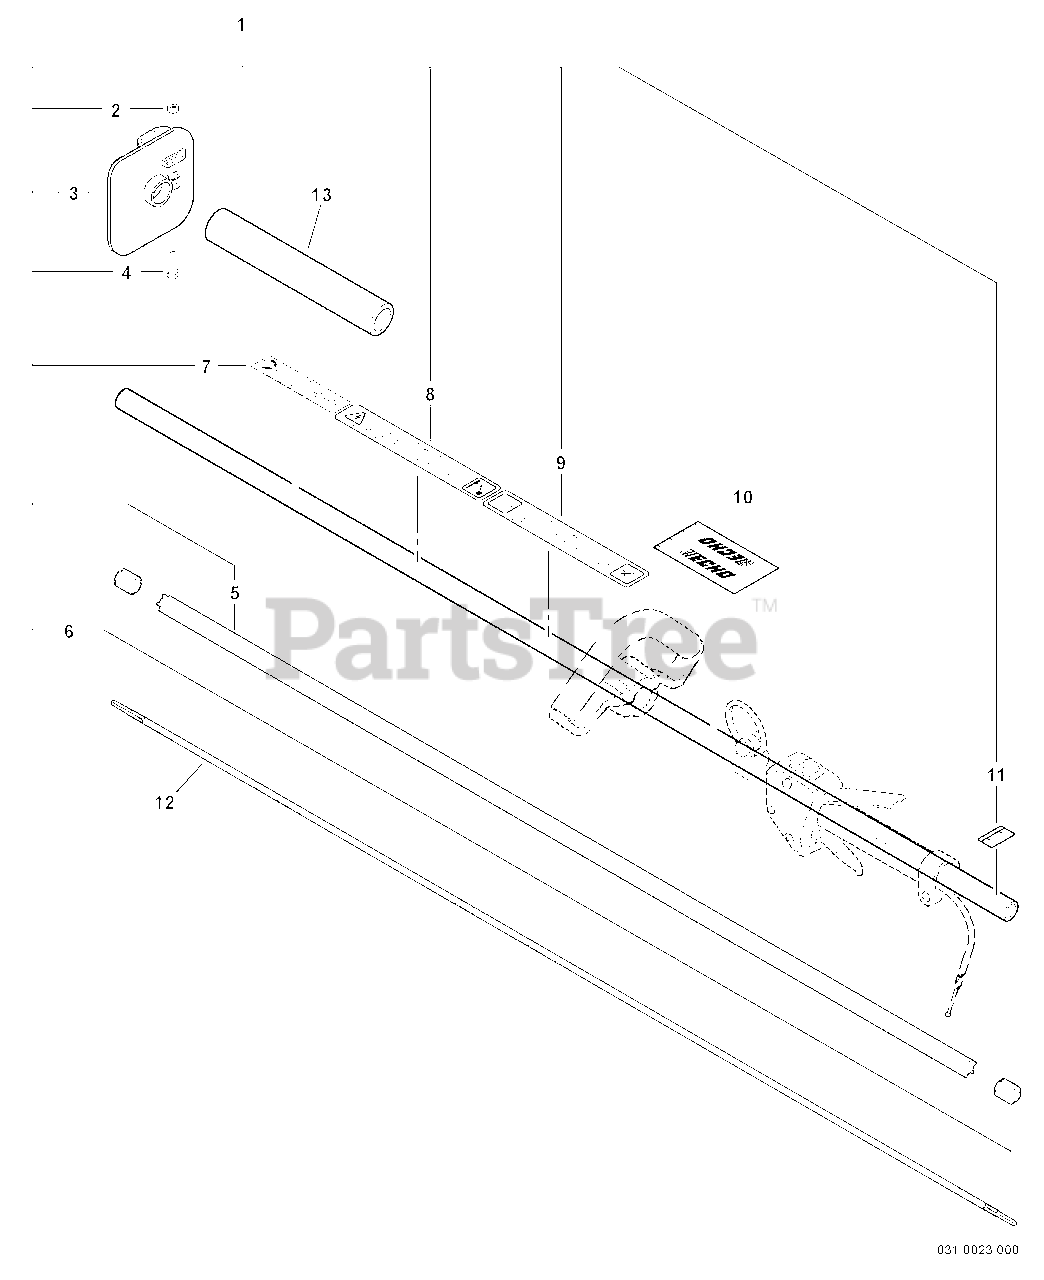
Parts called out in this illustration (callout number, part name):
1	MAIN PIPE ASSY
2	NUT M5
3	GUARD, HAND
4	BOLT 5×20
5	LINER, FLEXIBLE 21.6×1420
7	LABEL, CAUTION
8	LABEL - CAUTION
9	LABEL, CAUTION
10	LABEL, HANDLE LOCATION
11	LABEL - ALIGNMENT
12	DRIVESHAFT - FLEXIBLE L= 1522
13	GRIP, HANDLE
